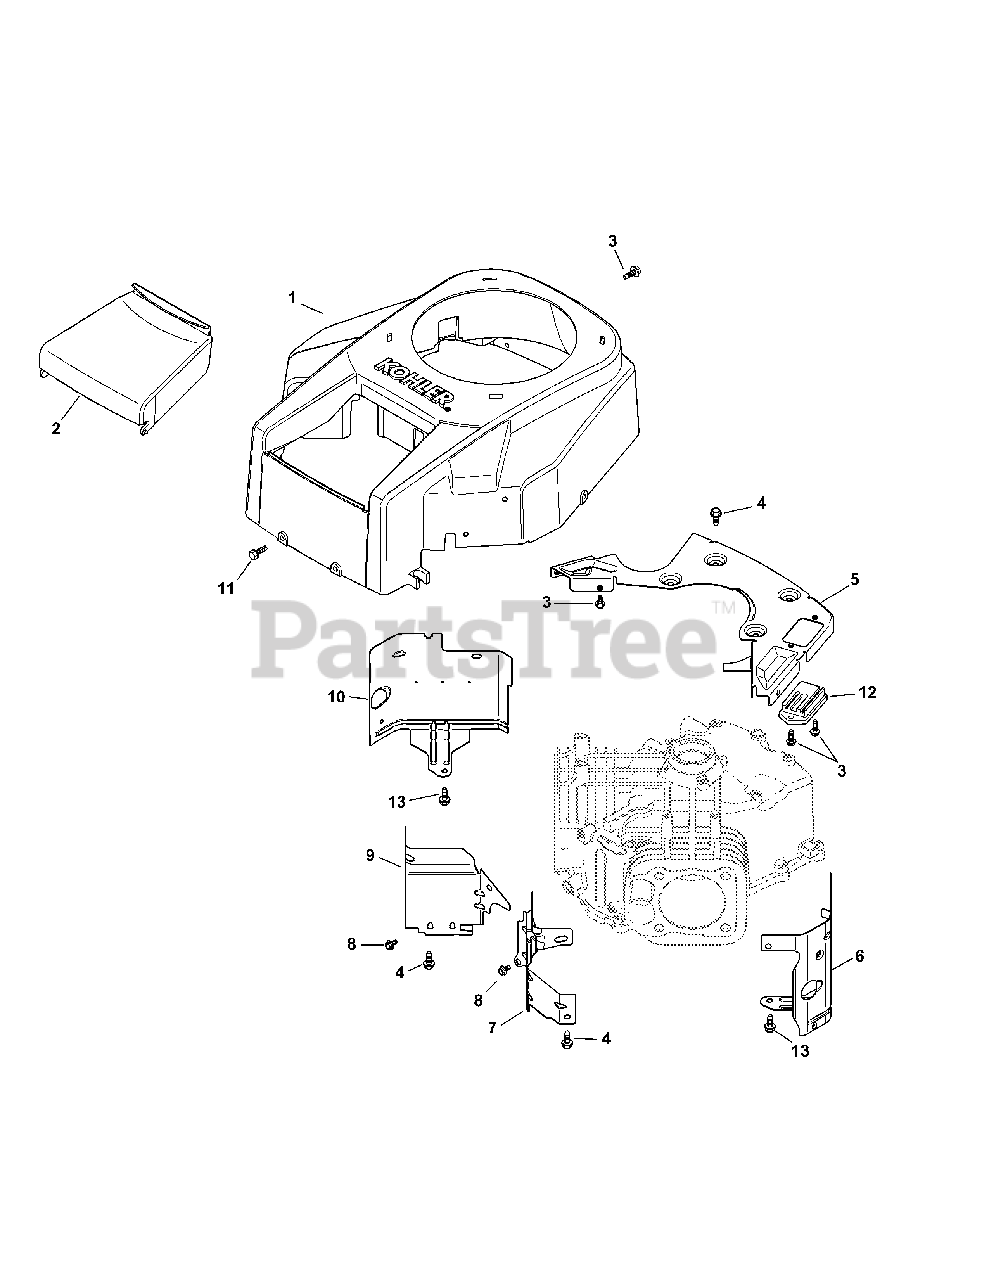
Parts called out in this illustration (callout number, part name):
1	Blower Housing Kit (Fixed Guard)(Inc. KH-41-037-10-S)
2	Air Cleaner Cover
3	Flange Screw, M5 x .8 x 16
4	Flange Screw, M6 x 1.0 x 16
5	Backing Plate Kit
6	Cylinder Barrel Baffle, #2 Side
7	Valley Baffle, #2 Cylinder
8	Flange Screw, M5 x .8 x 10
9	Valley Baffle, #1 Cylinder
10	Cylinder Barrel Baffle, #1 Side
11	Tap Screw, M6 x 1.7 x 18
12	Regulator/Rectifier
13	Screw, M6 x 1.0 x 10
